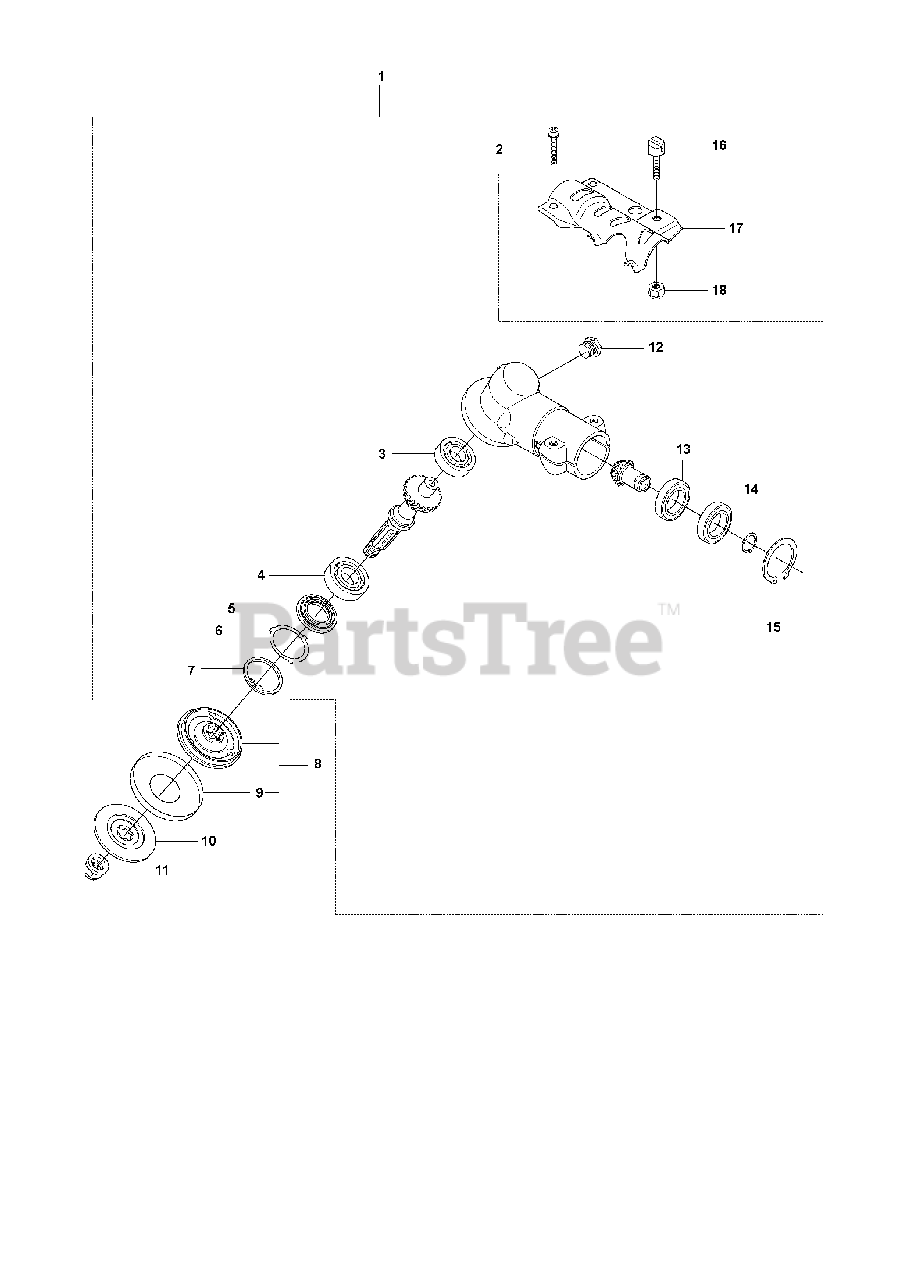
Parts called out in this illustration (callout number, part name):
1	%GEAR ASSY
2	SCREW
3	BALL BEARING
4	BALL BEARING
5	SEAL
6	WASHER
7	RETAINING RING SGH 35
8	RP CARRIER
9	RP TUBE INSERT
10	SUPPORT FLANGE
11	NUT BLADE
12	PLUG
13	BALL BEARING
14	RETAINING RING SGA 15
15	RETAINING RING
17	BRACKET
18	LOCKNUT M6
